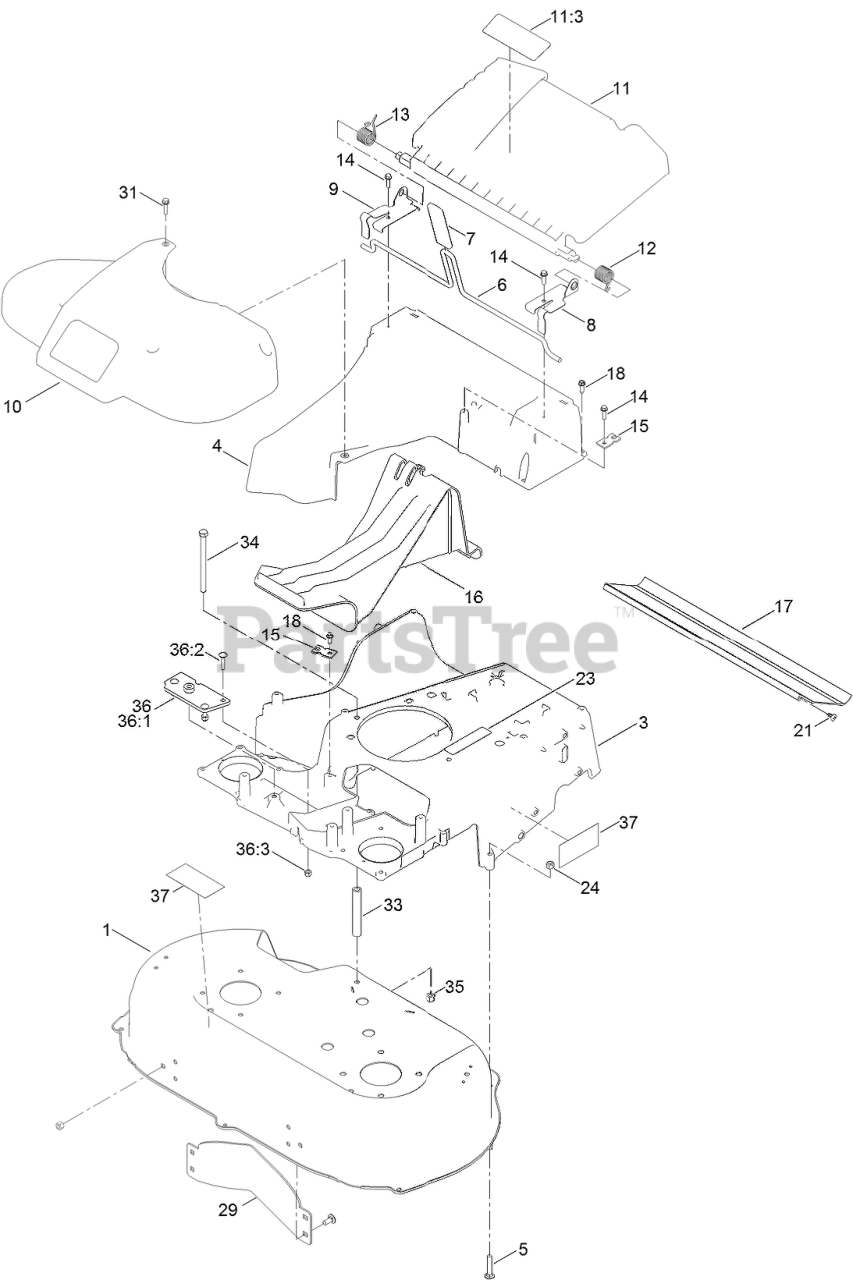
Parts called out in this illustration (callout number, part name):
1	HOUSING ASM
3	FRAME
5	BOLT-CAR
6	ROD-RELEASE, HANDLE
7	GRIP-LEVER
8	BRACKET-DOOR, LH
9	BRACKET-DOOR, RH
10	BELT COVER ASM
11	REAR DEFLECTOR ASM
11:3	DECAL-WARNING
12	SPRING-TORSION
13	SPRING-TORSION
14	SCREW-HWH
16	PLUG-MULCH
17	SHIELD-TRAILING
18	SCREW-HWHTF
21	SCREW-PTH
23	DECAL-ARRESTER, SPARK
24	NUT-LOCK, NI
29	BAFFLE-CONTROL
31	SCREW-HWHTF
33	SPACER-SHIELD
34	SCREW-HH
35	NUT-LOCK, NI
36	FRAME PLATE KIT
